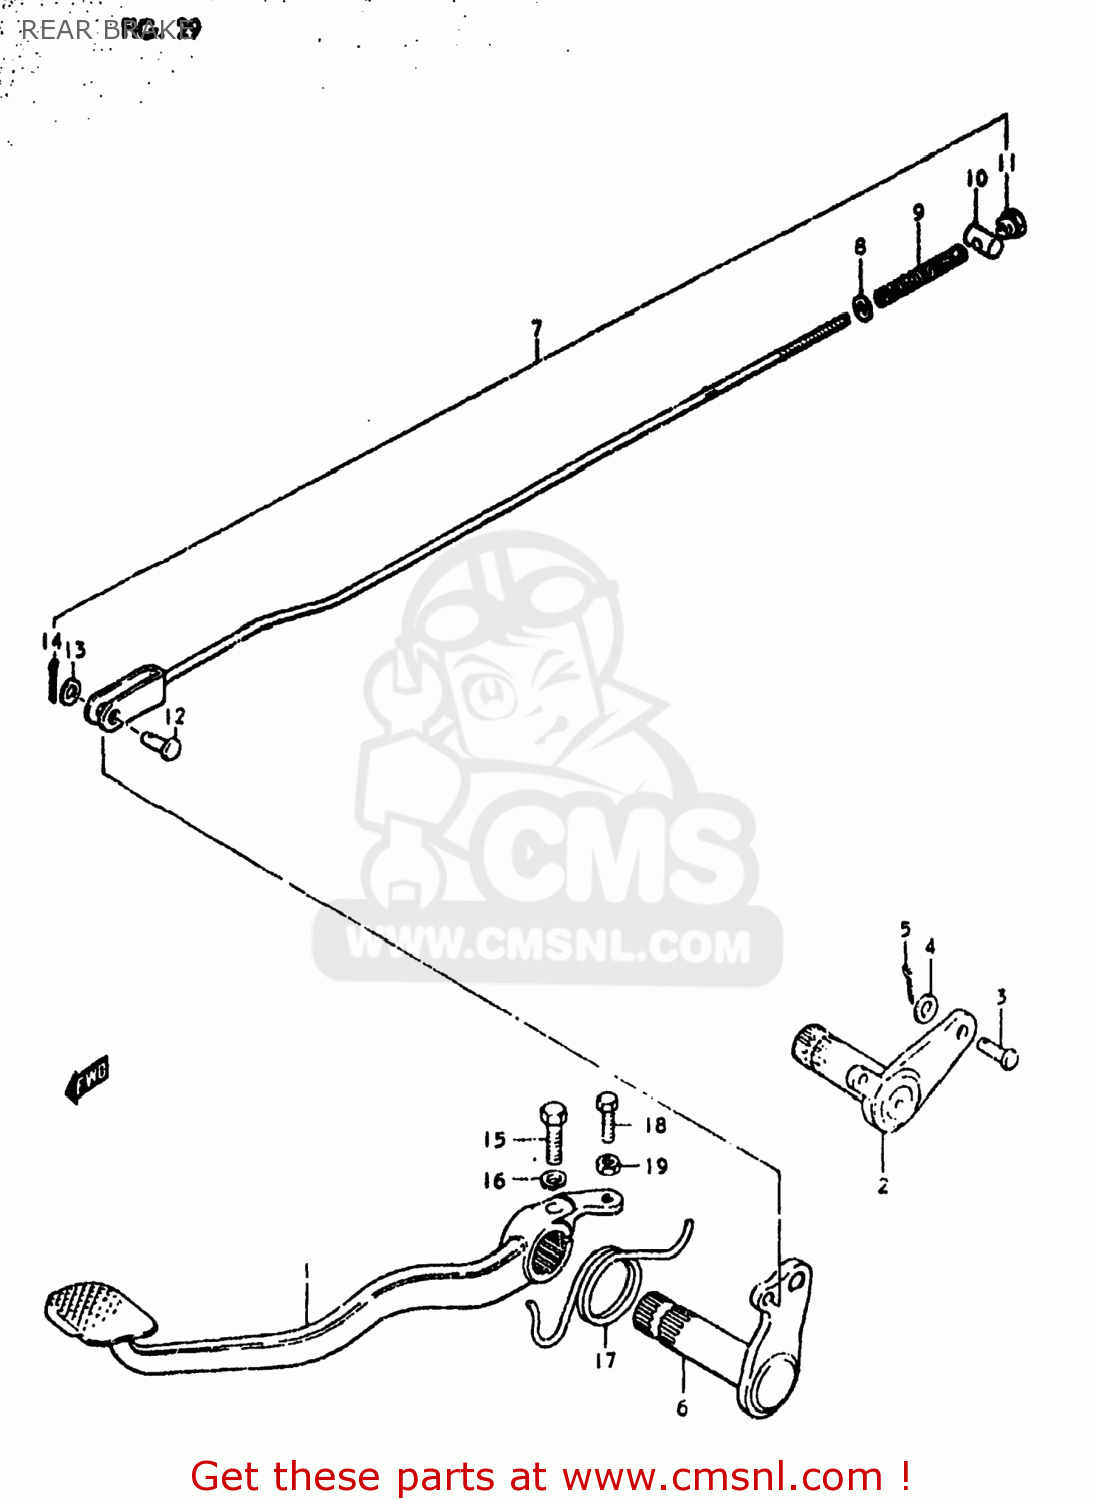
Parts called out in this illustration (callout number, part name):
1	PEDAL,BRAKE
2	ARM,BRAKE PEDAL ROD
3	PIN
4	WASHER
5	PIN
6	ARM,BRAKE PEDAL
7	ROD ASSEMBLY,REAR BRAKE
8	WASHER
9	SPRING
10	PIN
11	NUT
12	PIN(L:13.5)
13	WASHER
14	PIN 20X20
15	BOLT
16	LOCK WASHER
17	SPRING
18	BOLT
19	NUT
